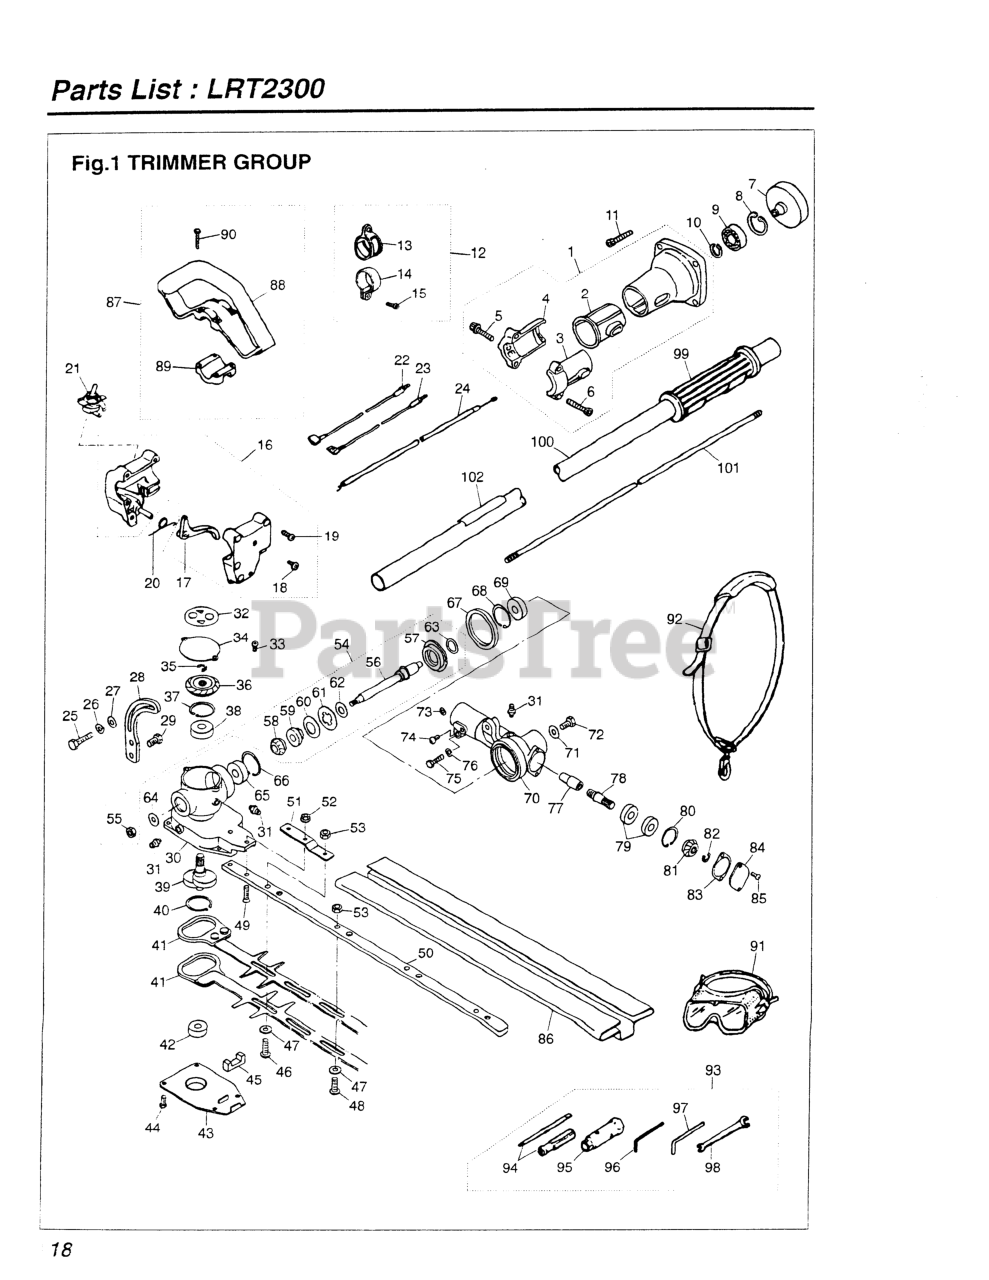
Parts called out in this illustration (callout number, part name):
2	CUSHION
3	BRACKET (USE -31211)
4	BRACKET (USE -31221)
5	BOLT (USE 3310-31720)
6	BOLT, M5 X 30
8	RING, SNAP, M28 x 1.2
9	BEARING
10	RING, SNAP (RPLS 3130-13270)
11	BOLT, M6 x 20
12	HANGER COMPLETE
13	HANGER
14	CLAMP
15	SCREW, M5 x 25
17	LEVER, THROTTLE
18	SET SCREW, ANTI-ROTATION
19	SCREW
20	SPRING, THROTTLE TRIGGER
21	SWITCH, STOP
22	CORD, RED (LEAD WIRE)
23	CORD, BLACK (LEAD WIRE)
24	CABLE COMP
26	WASHER, M6 X 15
27	WASHER, 6 X 6 X 2.0
28	ADJUSTER, ANGLE (USE-13141)
31	FITTING, GREASE
33	SCREW, M4 X 8
35	RING, SNAP
36	GEAR, BEVEL
37	RING, SNAP, M26 X 1.2
38	BEARING
39	CRANKSHAFT
40	RING, SNAP, M28 X 1.5
42	BEARING
44	BOLT, M4 X 8
45	FELT
47	WASHER (RPLS 3873-11760)
48	SCREW
49	SCREW, M5 X 20
50	PLATE, GUIDE
51	PLATE (RPLS 6780- )
52	NUT, M5
53	NUT, M6
54	KIT, SHAFT (RPLS 6782-13610)
55	NUT, M6 X 5
56	SHAFT
57	GEAR (B)
58	GEAR (C)
59	BOSS
60	WASHER, SPRING
61	PLATE
62	WASHER
63	WASHER
64	WASHER, 6X15X2.0
65	BEARING
66	RING, SNAP, M22 x 1.2
67	O-RING
68	RING, SNAP, M26 X 1.2
69	BEARING
70	CASING
71	WASHER, 6 X 6 X 2.0
73	WASHER
74	SCREW, M5 x 10
75	BOLT, M5 X 25
76	WASHER, M5 x 10
77	JOINT (REPLACES T3078-13810)
78	SHAFT, GEAR
79	BEARING
80	RING, SNAP, M22 x 1.2
81	GEAR, BEVEL
82	RING, SNAP
83	PACKING
84	COVER, STOPPER KIT
85	SCREW, M4 X 8
86	COVER, BLADE
87	HANDLE ASSEMBLY
88	HANDLE
89	CLAMP
90	SCREW, M5 x 35
91	GOGGLE
92	SHOULDER STRAP ASSY
93	TOOL SET
94	SCREWDRIVER
96	WRENCH (TOOL)
97	BAR
98	SPANNER, 8 X 10 (RPLS 2540- )
102	DECAL
